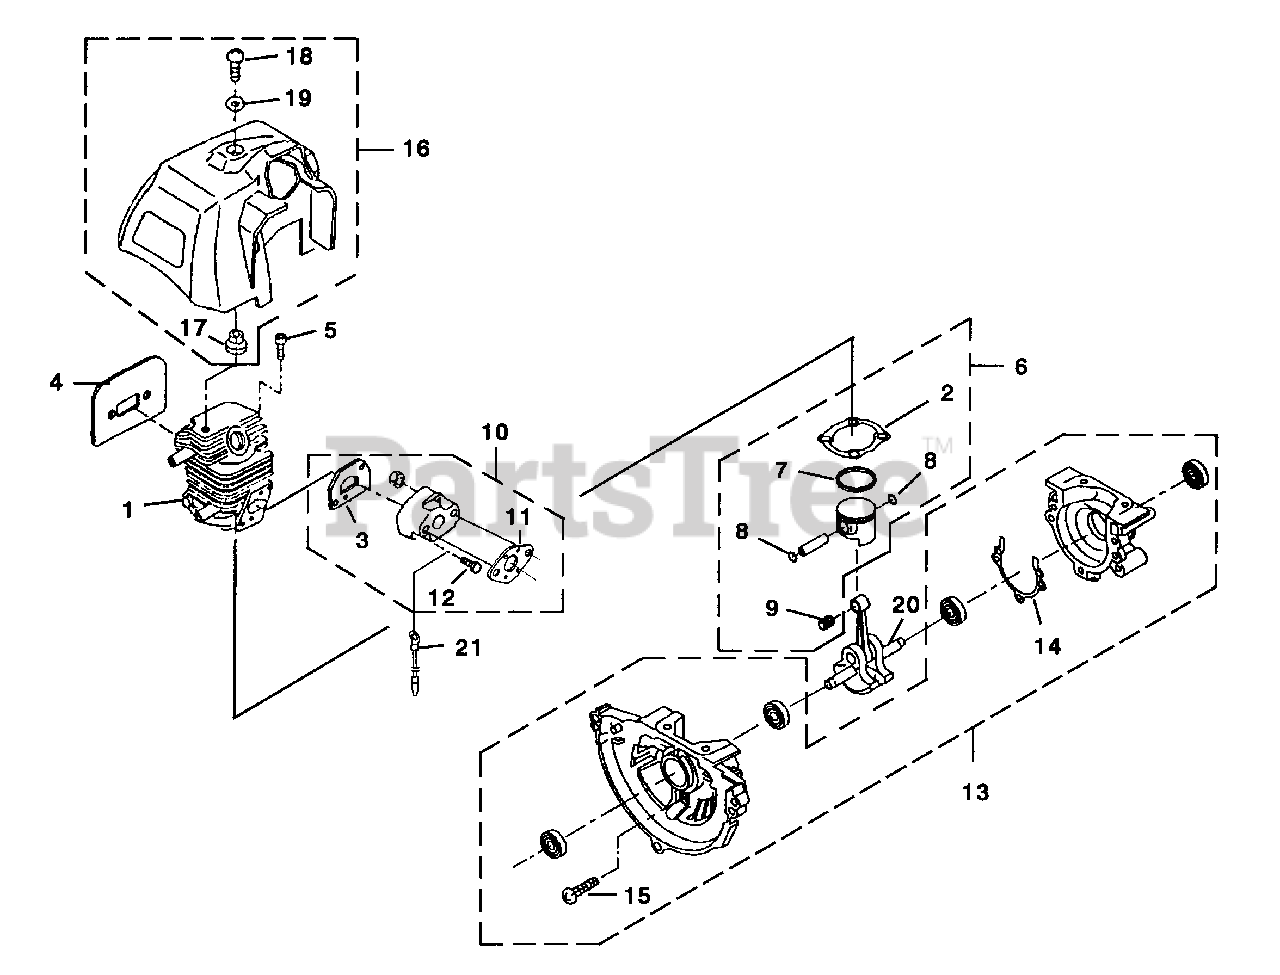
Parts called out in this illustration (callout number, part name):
1	CYLINDER KIT
2	GASKET-Cylinder
3	GASKET-Heat Dam
4	GASKET-Muffler
5	SCREW-Socket Hd (M5 x 20W SW)
6	PISTON ASSEMBLY
7	RING-Piston
8	RETAINER-Wrist Pin
9	BEARING-Wrist Pin
10	HEAT DAM ASSEMBLY
11	GASKET-Carburetor
12	SCREWS (M5 x 25 W SW)
13	CRANKCASE ASSEMBLY
14	GASKET-Crankcase
16	CYLINDER COVER ASSEMBLY
17	SPACER-Cylinder Cover
20	CRANKSHAFT & ROD
21	WIRE
